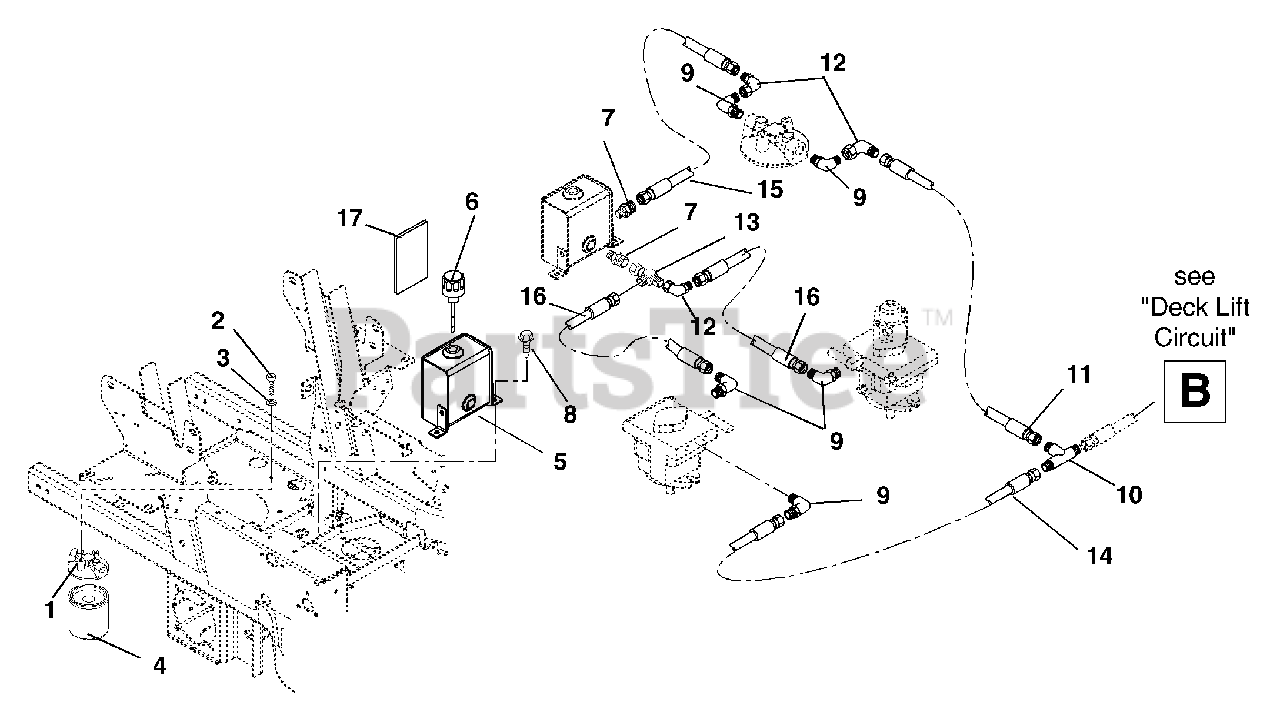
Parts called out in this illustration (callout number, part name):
1	Head-Filter
2	Bolt-Hex .25-20 x .50 Grade 5
3	Washer-Locking .25 x .062
4	Oil Filter
5	Tank-Hydraulic
6	Hydraulic Tank Dipstick
7	Adapter, Straight
8	Screw-Tapping .38-16 x .50 Hex Washer Head
9	Adapter
10	Adapter, Tee .56-18
11	Hose-Hydraulic
12	Adapter
13	Adapter, Pipe
14	Hose, Hydraulic
15	Hose,Hydraulic Valve To Tank
16	Hose, Hydraulic
17	Shield, Heat 5.50 x 4.50
